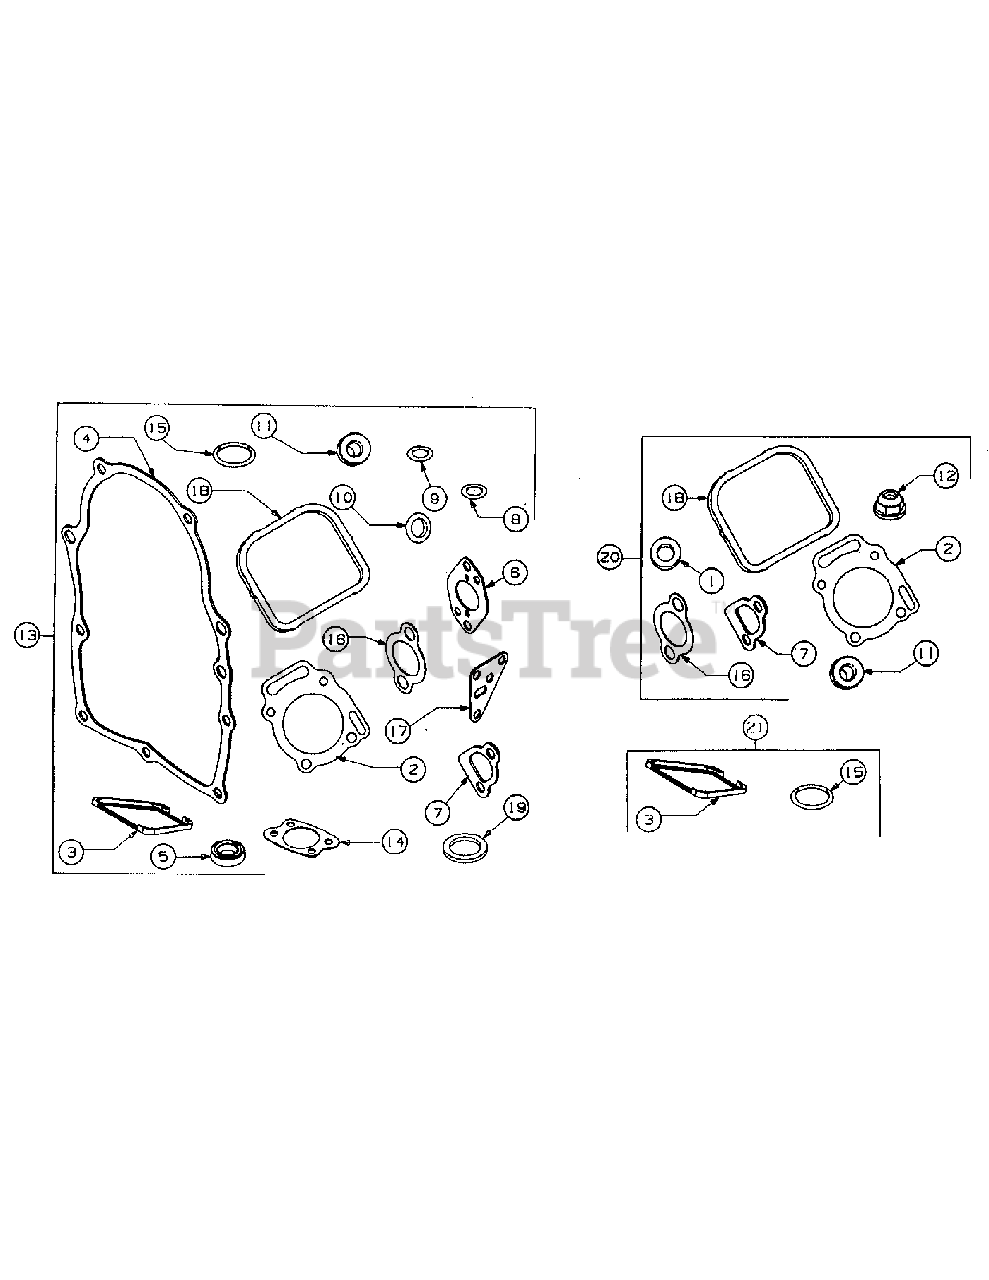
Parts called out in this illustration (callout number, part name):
1	Washer, Cylinder head
2	Gasket, Cylinder Head
3	Gasket, Breather
4	Gasket, Crankcase Cover
5	Seal, Oil
6	Gasket, Carburetor Mtg
7	Gasket, Intake Manifold
8	O-Ring
9	O-Ring
10	Gasket Sealing
11	Washer, Valve Cover
12	Nut, Nylock
13	Gasket Set
14	Gasket, Air Cleaner
15	Seal, Breather Screw
16	Gasket, Exhaust Manifold
17	Gasket, Oil Filter Adapter
18	Gasket, Valve Cover
19	Seal, Oil
20	Overhaul Kit, Valve
21	Gasket Set, Breather
